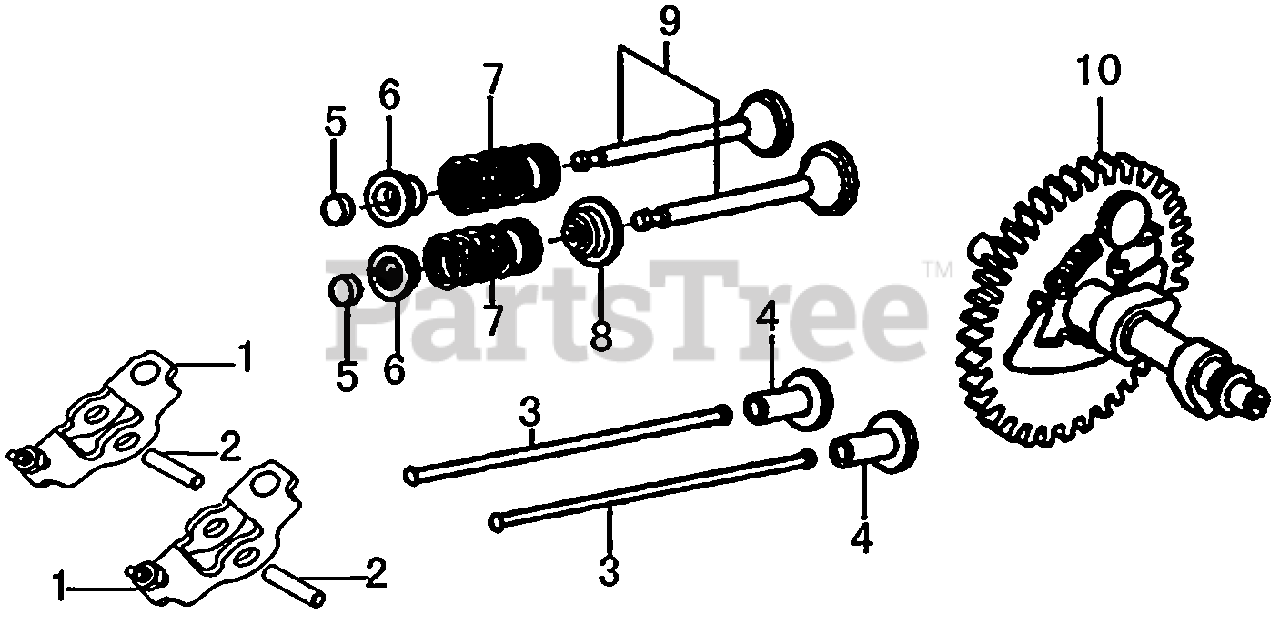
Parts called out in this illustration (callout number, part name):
1	ASSY, ROCKER ARM
2	VALVE ROCKER SHAFT
3	ROD, PUSH
4	LIFTER VALVE
5	ROTATOR, VALVE
6	RETAINER, VALVE SPRING
7	SPRING, VALVE
8	SEAL, GUIDE
9	VALVES, INTAKE & EXHAUST SET OF 2
10	CAMSHAFT ASSY.
